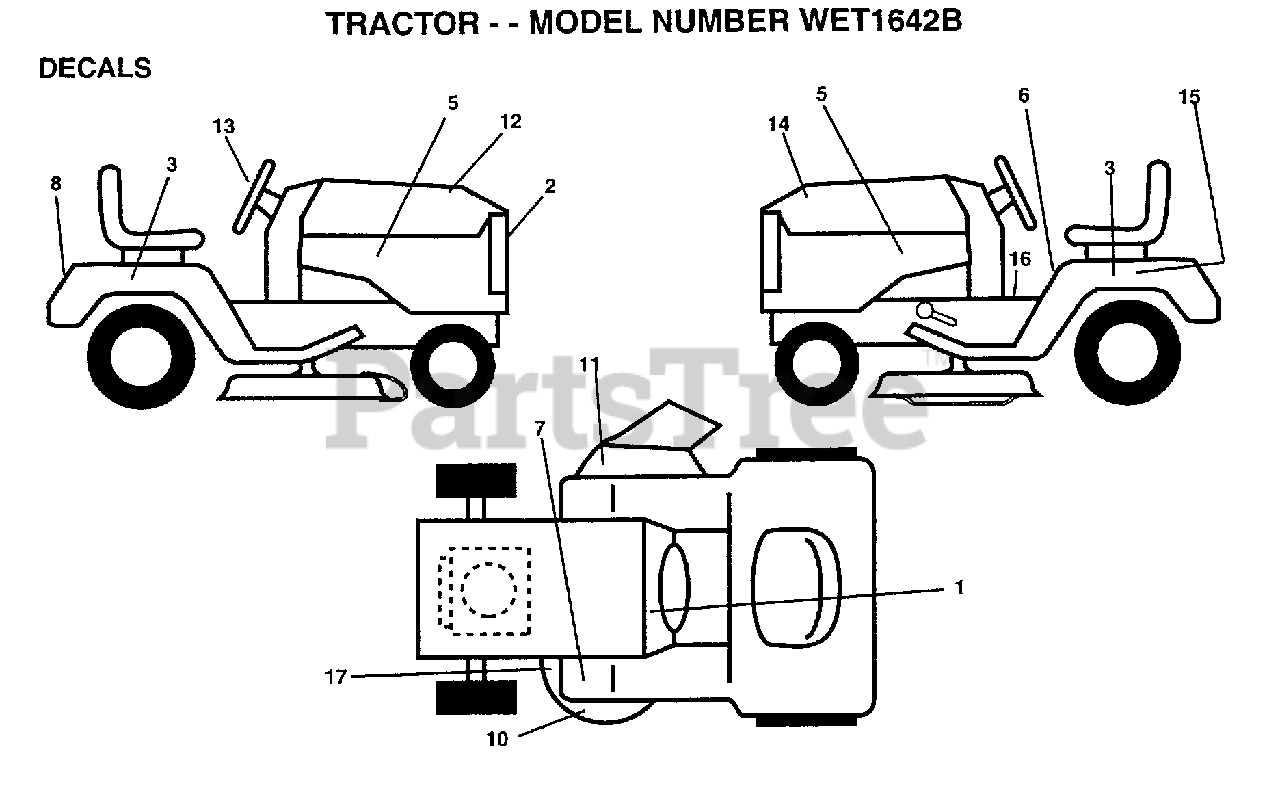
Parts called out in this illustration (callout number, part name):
1	DECAL.DASH.INSTR.
2	DECAL.GRILL
3	DECAL.FEND.QUICKS
5	DECAL.PNL.SD.WEED
6	DECAL CAUTION
7	DECAL T
8	DECAL.FENDER
10	DECAL.MOWER
11	"DECAL, WARNING"
12	DCL.HD.WET1642A
13	DECAL.WHL.STRG.
14	DCL.HD.WET1642A
15	DECAL.BTRY.DANGER
16	DECAL BRAK PARK
17	DECAL
